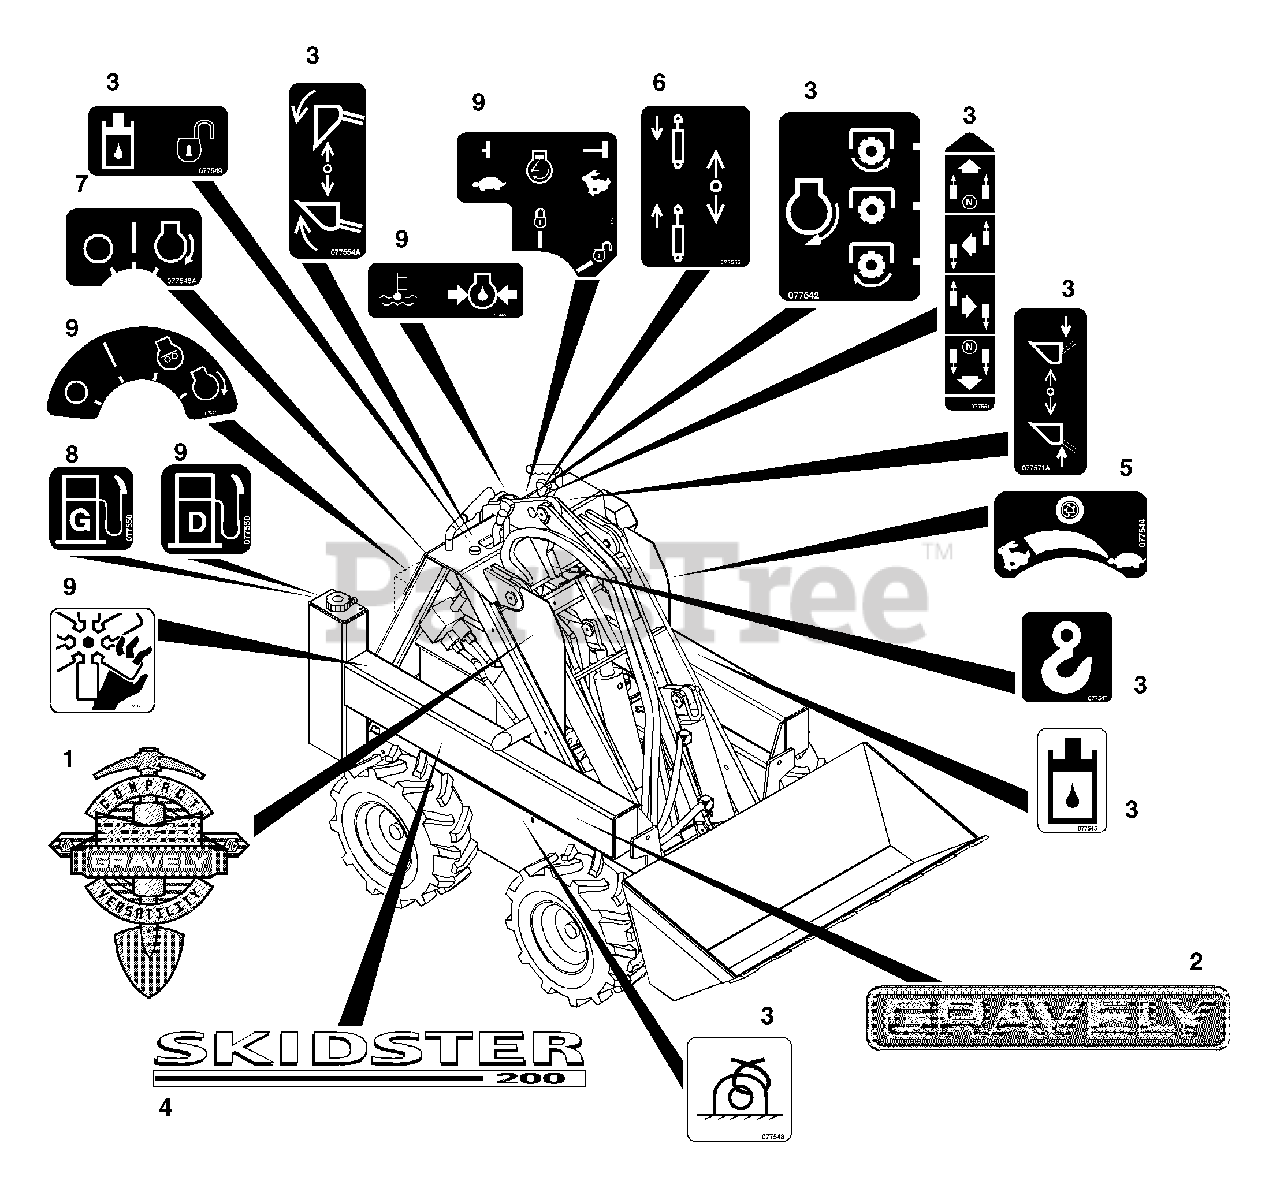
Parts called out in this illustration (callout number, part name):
1	Decal-Skidster Icon
2	Decal-Gravely
3	Decal-Set Skidster
4	Decal-Skidster 200
4	Decal, Skidster 200D
5	Decal-Ground Speed Control
6	Decal-Hydraulic Control
7	Decal-Ignition
8	Decal-Gasoline
9	Decal Set, Skidster Kubota Diesel
